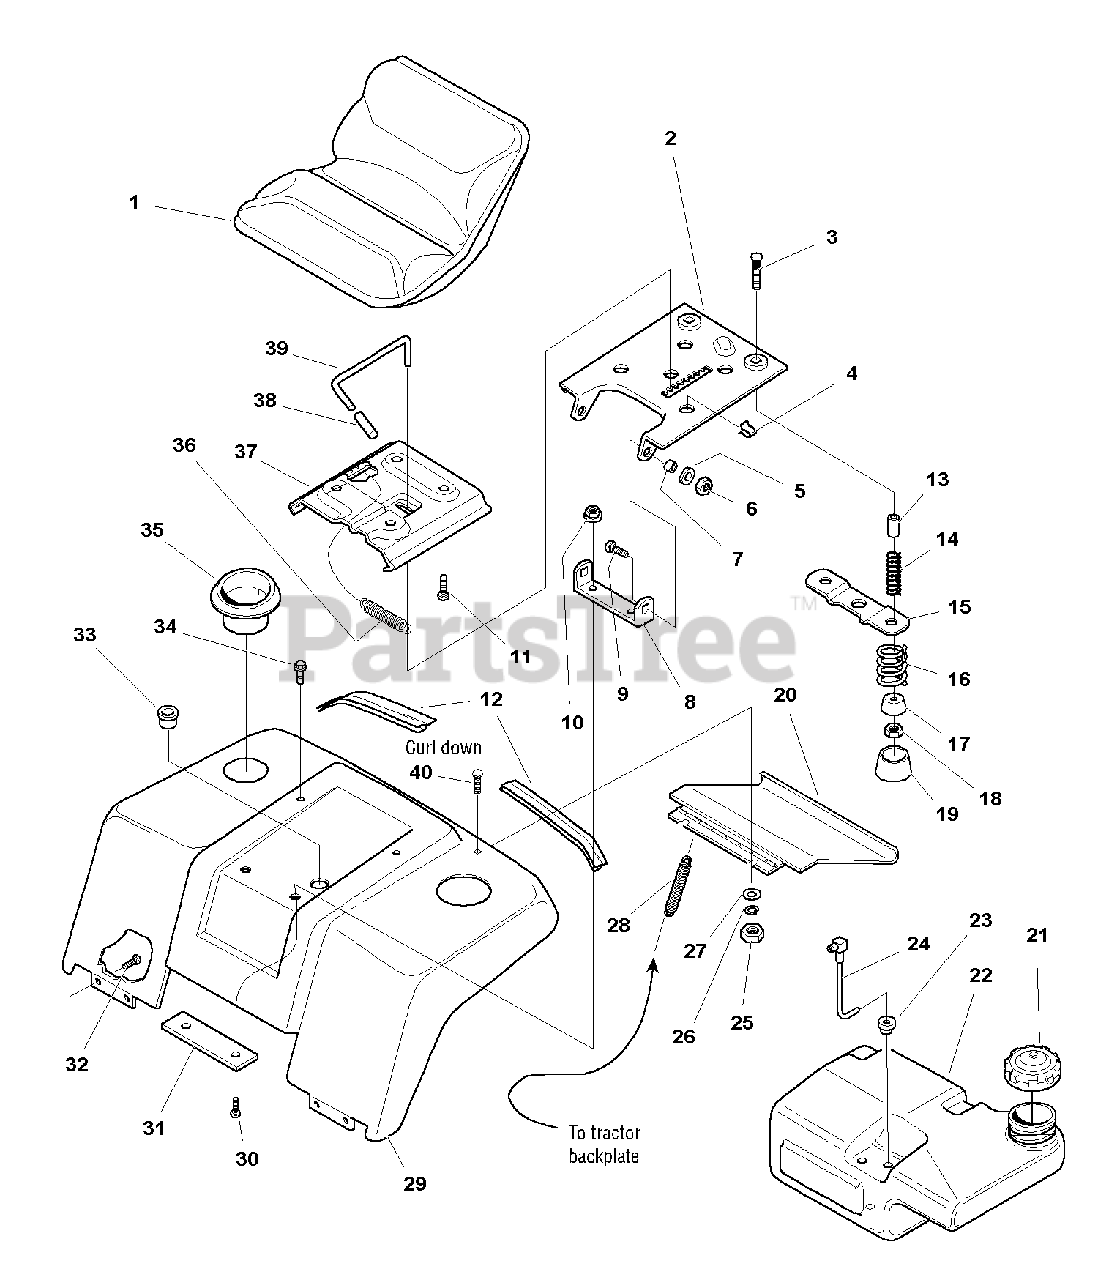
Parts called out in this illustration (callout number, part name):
1	SEAT, w/Cusion No Arms
2	SUPPORT, Seat Pivot
3	CARRIAGE BOLT, 5/16-18 x 2
4	CLIP, Speed Wire
5	WASHER, 3/8
6	NUT, Hex Lock ESNA Light, 3/8-16
8	BRACKET
9	CARRIAGE BOLT, 3/8-16 x 2
10	NUT, Hex Flange Whizlock, 3/8-16
11	CAPSCREW, Hex Flange Whizlock, 5/16-18 x 1/2
12	EDGING, 11 Long, Black Rubber
14	SPRING, Compression
15	PLATE, Switch
16	SPRING, Extension, Black
17	WASHER, Spring, Cone
18	NUT, Hex Lock ESNA Light, 5/16-18
19	COVER, Spring, Black Vinyl
20	DOOR & HINGE ASSEMBLY, Hopper
21	CAP, Fuel Tank, Black
23	BUSHING, Rubber
24	ELBOW & TUBE ASSEMBLY
25	NUT, Hex 1/4-20
26	LOCKWASHER, 1/4
27	WASHER, 1/4
28	SPRING, Extension
29	DECK & WELD STUDS ASSEMBLY, Seat, Red
29	DECK & WELD STUDS ASSEMBLY, Seat, Orange
30	CAPSCREW, Truss Head, Torx Drive, 3/8-16 x 1
32	CAPSCREW, Hex Washer Head, Taptite, 1/4-20 x 1/2
33	BUSHING, Snap
34	CAPSCREW, Hex Washer Head, Taptite, 5/16-18 x 5/8
35	HOLDER, Cup, Black Plastic
36	SPRING, Compression
37	SLIDE, Seat
38	GRIP, Black Vinyl
39	LEVER, Seat Release
40	CARRIAGE BOLT, 1/4-20 x 3/4
